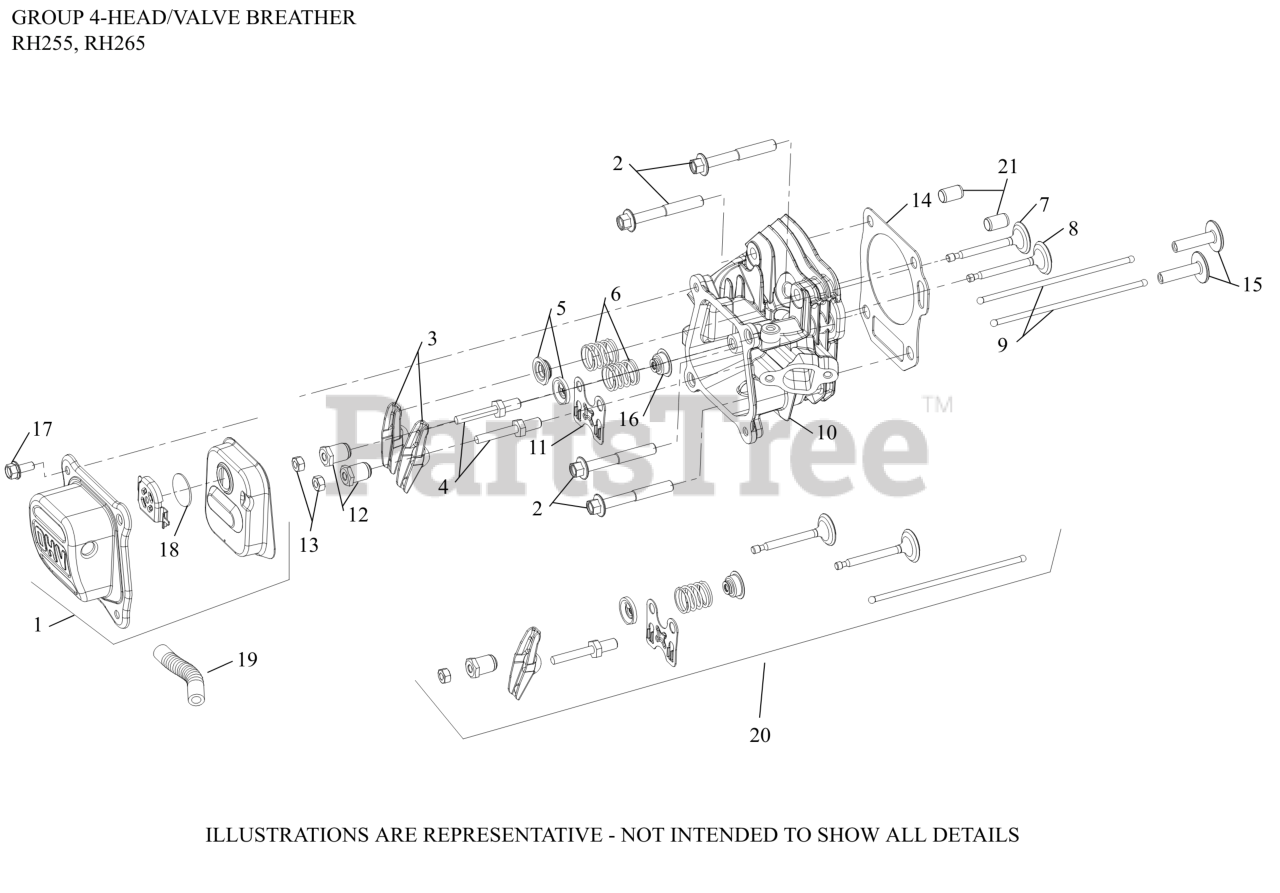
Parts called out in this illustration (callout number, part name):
1	COVER, VALVE ASSEMBLY
2	SCREW, HEX FLANGE CYL HEAD
3	ARM, ROCKER
4	STUD, ROCKER ARM-USE 14 072 22-S
5	RETAINER, VALVE SPRING
6	SPRING, VALVE
7	VALVE, EXHAUST
8	VALVE, INTAKE
9	ROD, PUSH
10	CYLINDER HEAD
11	PLATE, PUSHROD GUIDE
12	PIVOT, ROCKER ARM
13	NUT, HEX JAM
14	GASKET, CYLINDER HEAD
16	SEAL, VALVE
17	SCREW, HEX FLANGE (M6)-USE 25 086 433-S
18	REED, BREATHER
19	HOSE, BREATHER (LPAC)
20	KIT, VALVE TRAIN
